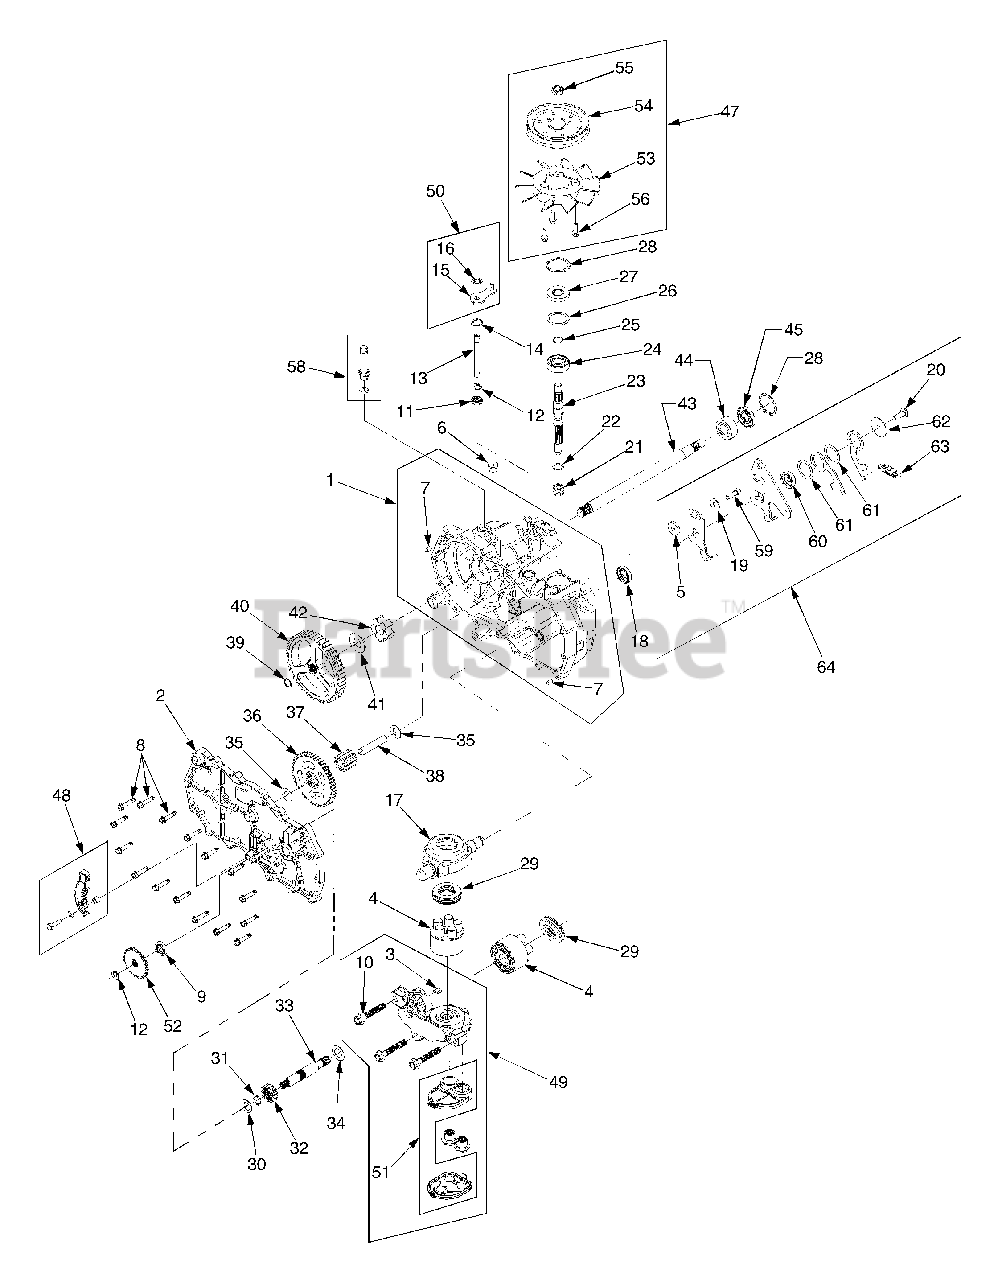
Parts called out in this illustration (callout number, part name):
1	Housing Assembly, Main LH
2	Side Assembly
3	Plate, Bypass
4	Block Assembly
5	Spacer, .32 x 1.005
7	Pin, Stainless
8	Screw, Hex Self Tapping, 1/4-20 x 1.25
9	Seal, Lip, .625 x 1.0 x .25
10	Bolt, Hex Flange, 3/8-24 x 2.5
11	Seal, Lip, .375 x .75 x .25
12	Ring, Retaining, .375 Ext.
13	Rod, Bypass
14	Ring, Retaining, .75 Int.
15	Arm, Bypass
16	Ring, Retaining, .375 Push
17	Swashplate, Trunnion
18	Seal, Lip, 18 x 32 x 7
19	Washer, Flat, 11/32 x 7/8 x 1/16
20	Screw, 5/16-24 x 1.0
21	Spring, Compression
22	Washer, .591 x .787 x .04
23	Shaft, Input
24	Bearing, Ball, 17mm x 40 x 12
25	Ring, Wire Retaining, .561
27	Seal, Lip, 17 x 40 x 7
28	Ring, Retaining
29	Bearing, Thrust, 30 x 52 x 13
30	Washer, Flat, 5/8 x 1.0 x .05
31	Ring, Retaining
32	Gear, Pinion, 13T
33	Shaft, Motor
34	Washer, .71 x 1.16 x .04
35	Washer, HT, .5 x 1.0 x .032
36	Gear, 10T/48T
37	Gear, Jackshaft, 10T
38	Pin, Jackshaft
39	Ring, Spiral Retaining
40	Gear, Bull, 52T
41	Washer, 3/4 x 1.5 x .13
42	Bearing, Sleeve
43	Axle, spline
44	Bushing, .752 x 1.571 x .625
45	Seal, Lip, .75 x 1.577 x .25
46	Kit, Expansion Plate
47	Kit, Fan-Pulley
48	Kit, Brake Arm
49	Kit, Center Section-Filter
50	Kit, Bypass Arm
51	Kit, Filter
52	Disc, Brake Cog
53	Fan, 6" 10 Blade
54	Pulley, 4.5
55	Nut, Hex Insert Lock, 1/2-20
56	Screw, Hex Wash. Hd. Tapp 1/4-20
58	Fitting/O-ring Assembly
59	Screw, Patch, 5/16-24 x 1.0
60	Bushing, Pilot, 1.125
61	Washer, Plastic
62	Washer, 1.5 x .34 x .062
63	Spring, Extension
64	Kit, Return Assembly LH
